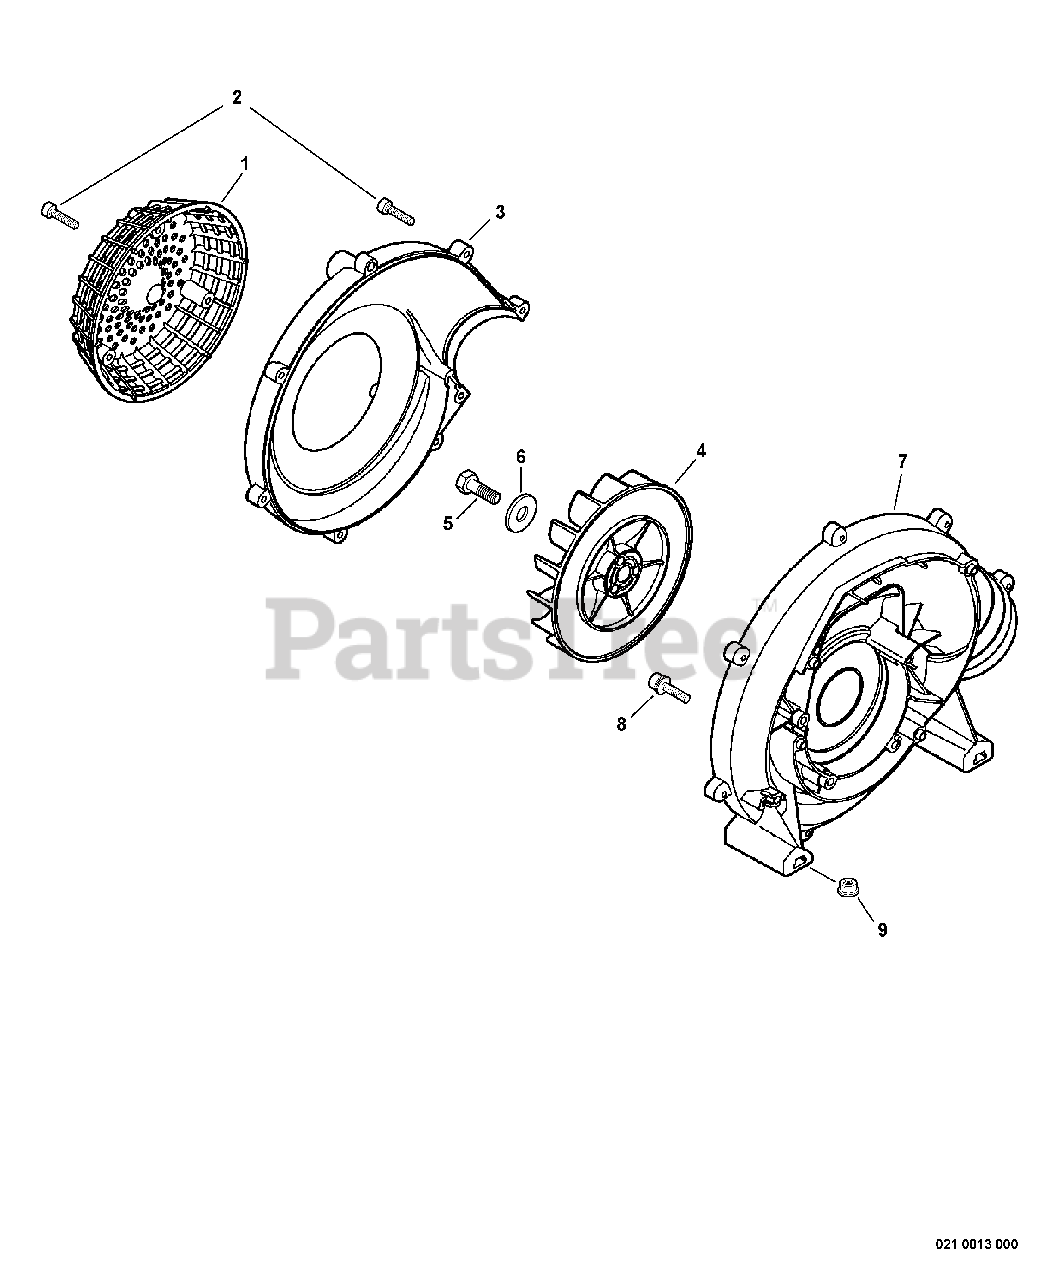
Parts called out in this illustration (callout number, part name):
1	GUARD, DEBRIS
2	SCREW TAPPING 5×20
3	COVER, FAN
4	FAN
5	BOLT 8×14
6	WASHER 8.2×31×0.8
7	CASE, FAN
8	BOLT 4×20
9	NUT, FLANGE M5
